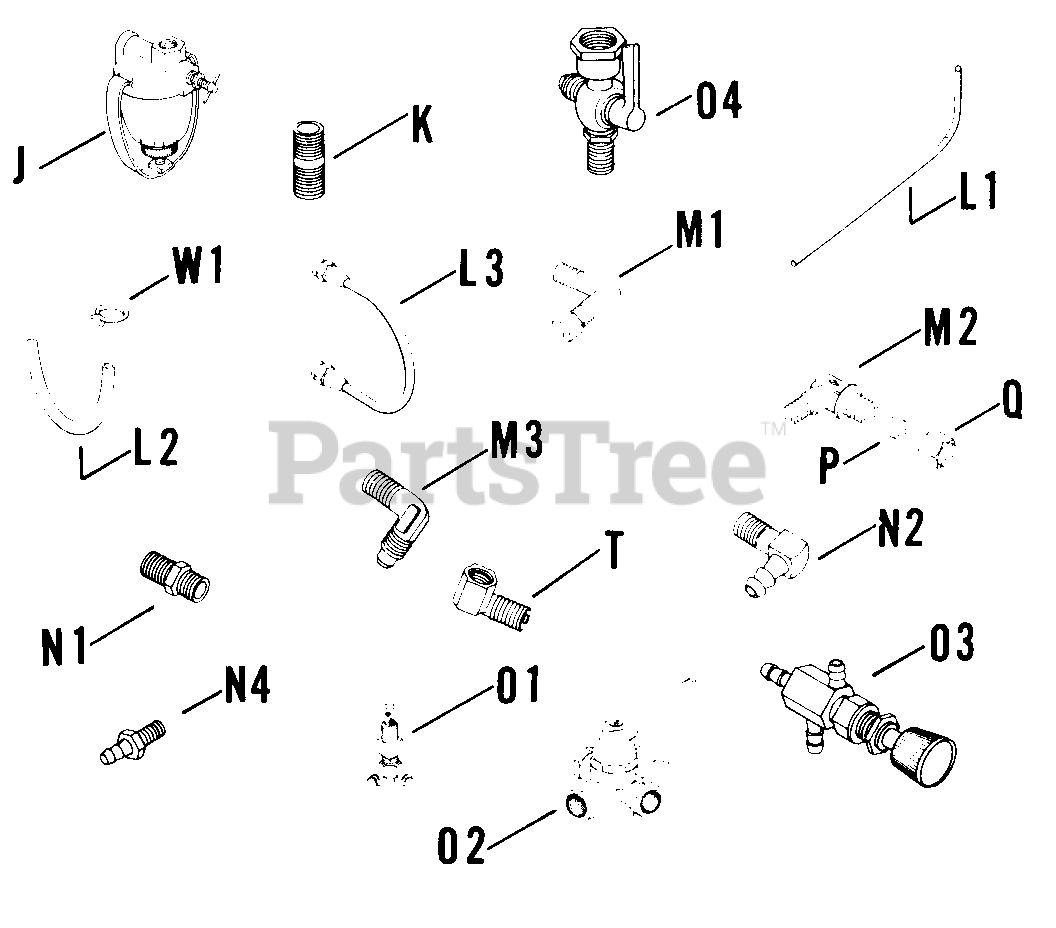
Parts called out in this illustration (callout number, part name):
J	KIT - USE 25 755 22
K	NIPPLE, PIPE 1/8 X 3/4 USE 25 136 23-S
L2	LINE - USE X-697-8
N2	HOSE - USE 25 155 02
W1	CLAMP HOSE USE X-426-9
